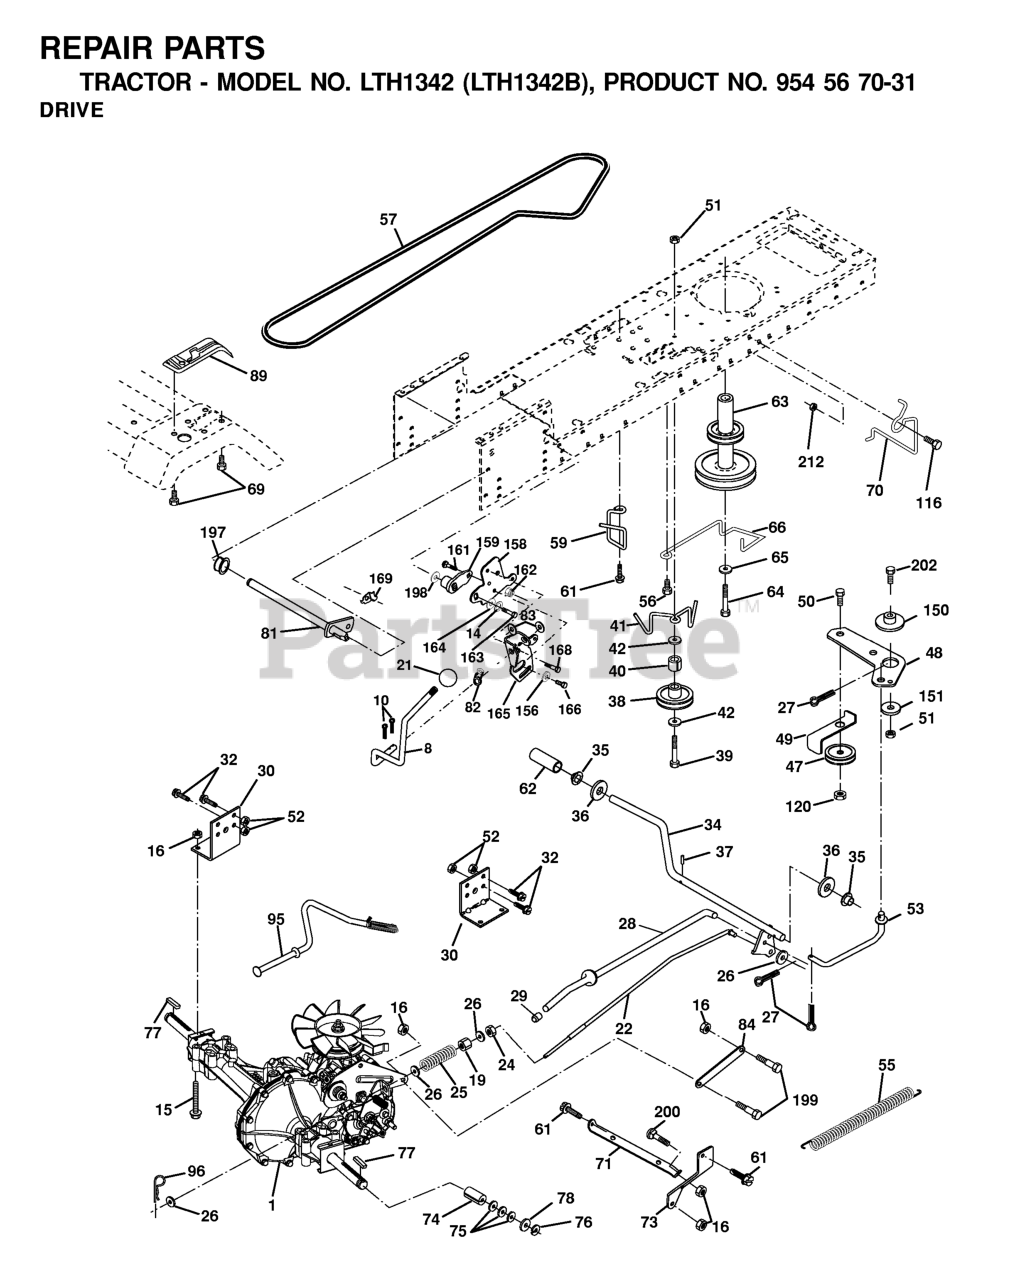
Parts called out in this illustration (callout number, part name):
8	ROD.SHIFT.FENDER.ADJ.LT.CRD
10	PIN COTTER
14	LOCKWASHER
15	BOLT HEX 5/16-18 GR 5
16	NUT.71038.31-18.HEX.NYLOCK
19	NUT
21	KNOB.DELUXE.(PISTOL.GRIP).BLAC
22	ROD BRAKE HYDRO
24	NUT
25	SPRING ROD LT
26	WASHER
27	COTTER PIN
28	ROD, PARKING BRAKE
29	PLUNGER CAP
30	BRKT, MOUNT TRNSAXLE
32	BOLT
34	SHAFT, FOOT PEDAL
35	BEARING.NYLON
36	WASHER LT
37	DRIVE PIN
39	BOLT
40	SPACER, SPLIT
41	KEEPER, BELT IDLER
42	WASHER
47	IDLER PULLEY
48	BELLCRANK, CLUTCH
49	RETAIN BELT
50	BOLT
52	LOCKNUT
53	LINK, CLUTCH LT
55	SPRING, RETURN LT
56	SCREW THDROL 3/8-16 X 1-1/2
57	DRIVE BELT, LTH & YTH TRACTORS
59	KEEPER, BELT CENTER
61	SCREW 3/8-16X3/4
62	PEDAL COVER T
63	ENGINE PULLEY
64	BOLT
65	LOCKWASHER
66	KEEPER BELT ENGINE
69	SCREW.HI-LO.CONSOLE
70	KEEPER BELT ENG
71	STRAP TORQUE LH HYDRO
73	STRAP TORQUE RH HYDRO
74	SPACER AXLE
77	SQUARE KEY
81	SHAFT ASM CROSS TAPERED
82	SPRING,TORSION
83	WASHER
84	LINK TRANSAXLE
89	CONSOLE, SHIFT
95	CONTROL ASM. BYPASS HYDRO
96	RETAINER M
103	NUT.HEX.1/2-20
116	BOLT D
120	NUT LOCK FLG 3/8-16 UNC
150	SPACER, RETAINER
151	WASHER 12/32X2X10GA
156	WASHER.SRRTD.5/16
158	BRACKET
159	HUB
161	BOLT
162	NUT.CROWNLOCK.1/4
163	BOLT
164	Washer 5/8 x .281 x 10 Ga.
165	RP BRACKET
168	BOLT.SHOULDER.5/16-18X
169	PLATE.FASTENING.CROSS.SHAFT
197	NYLINER SNAP 5/8" ID
198	WASHER.NYL.7/8IDX.105"HYD CR
199	BOLT SHOULDER 5/16-18 UNC
200	BOLT
205	WASHER
212	NUT
